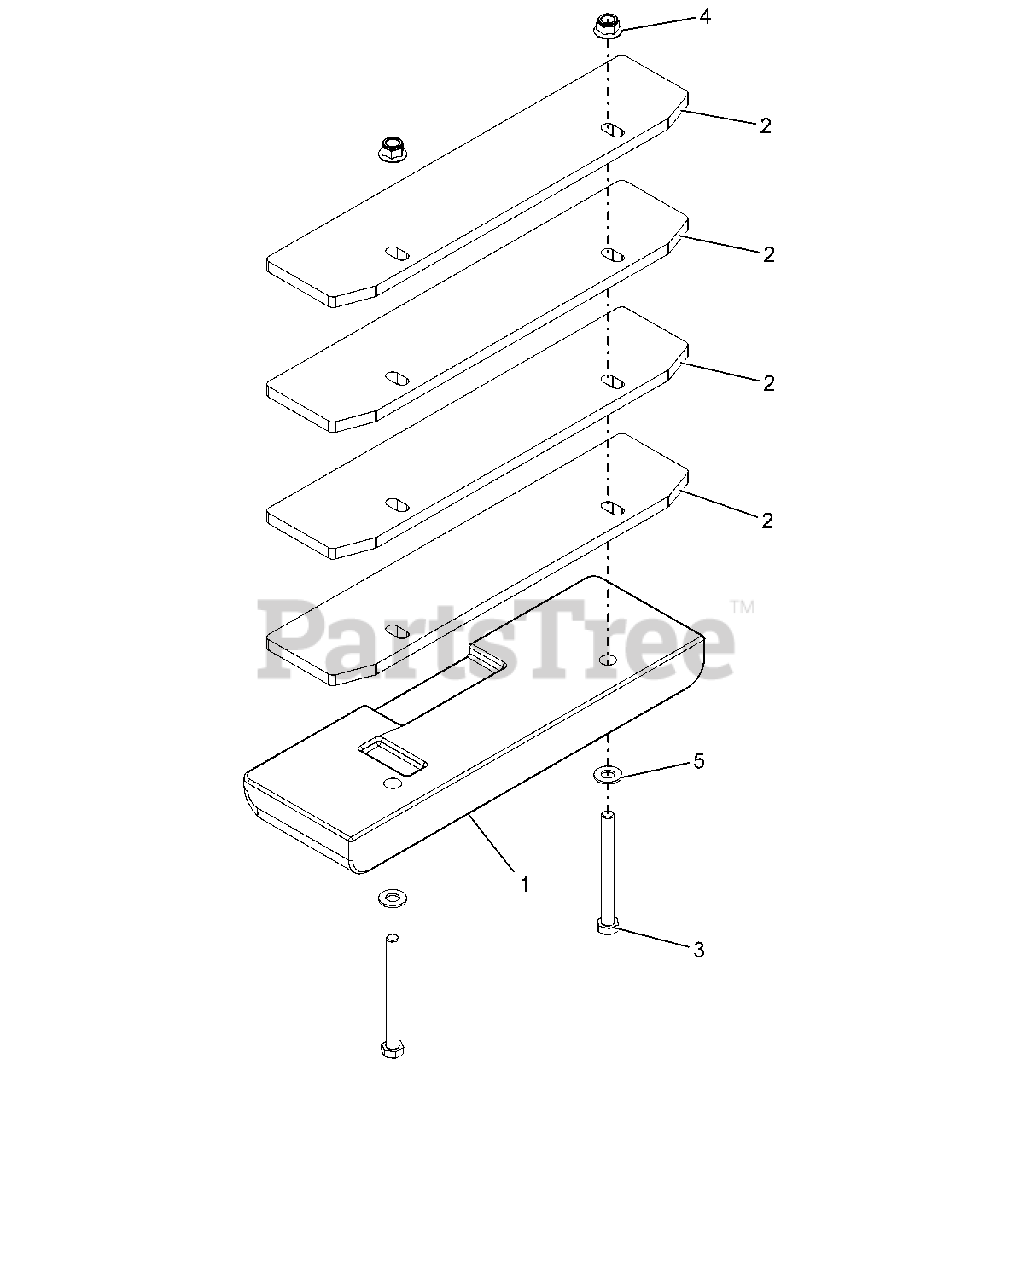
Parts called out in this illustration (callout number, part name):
1	WEIGHT, CAST IRON
2	PLATE, COUNTER WEIGHT
3	@BLT-HEX .50-13X5.00 GR5 YWZC
4	@NUT-LK-NYL-FLG .50-13 YWZC
5	@WSHR-FL-STL.531X1.06X.095YWZC
